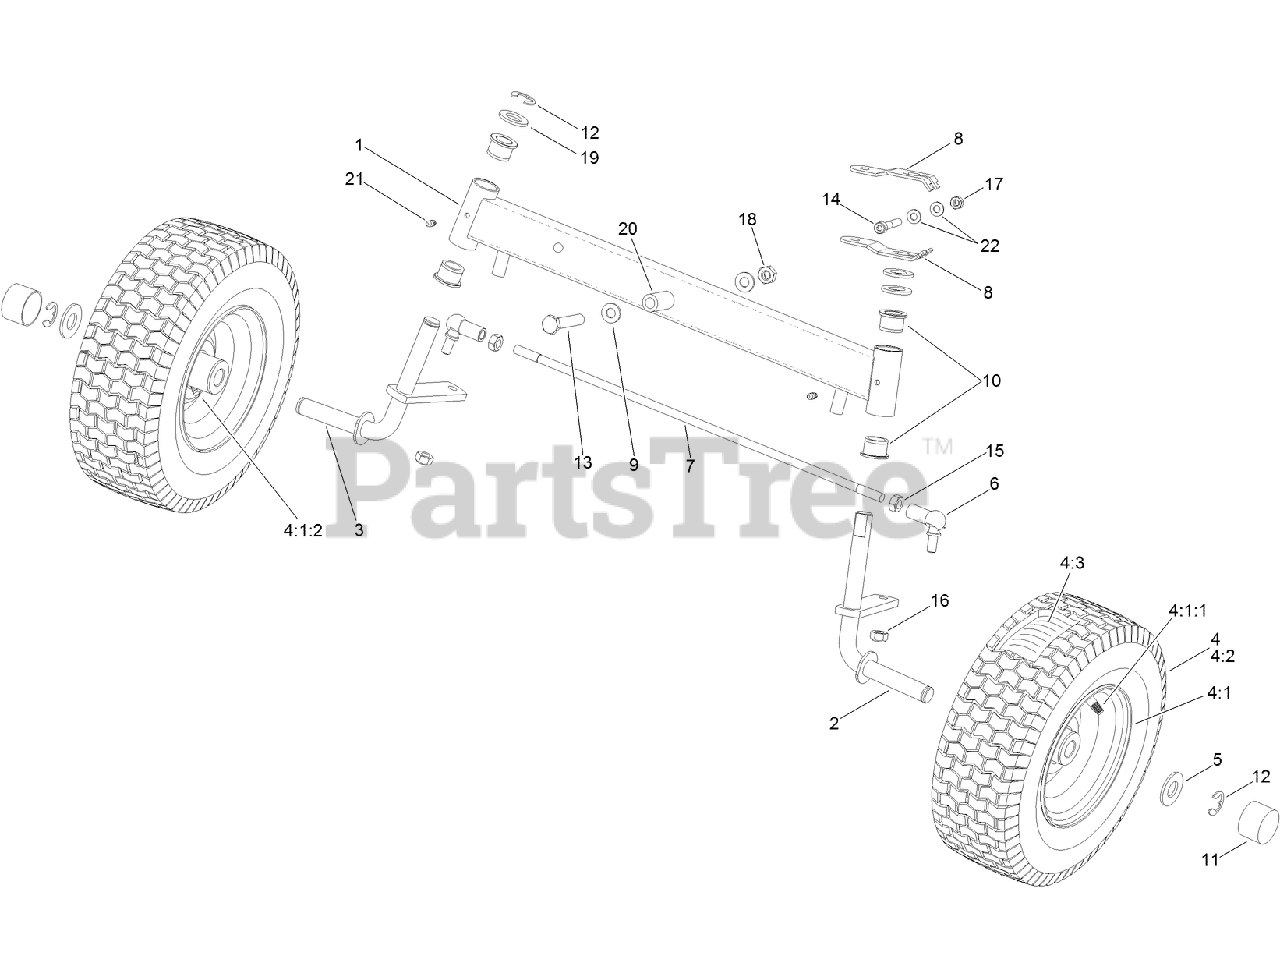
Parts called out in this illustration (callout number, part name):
1	FRONT AXLE ASM
2	SPINDLE-LH
3	SPINDLE-RH
4	Loose Parts Package
4:1	FRONT RIM ASM
4:1:1	Valve-Tire
4:1:2	FITTING-GREASE
5	WASHER
6	JOINT-BALL, ANGLE
7	TIE ROD-AXLE, FRONT
8	LEVER-SPINDLE, STEERING
9	SPACER
10	BUSHING-SWIVEL
11	CAP-HUB
12	CLIP-SPRING
13	SCREW-HH
16	NUT-LOCK
17	NUT-LOCK, NI
18	NUT-LOCK, HEX NI
19	WASHER-FLAT
21	FITTING-GREASE
22	WASHER-PLAIN
